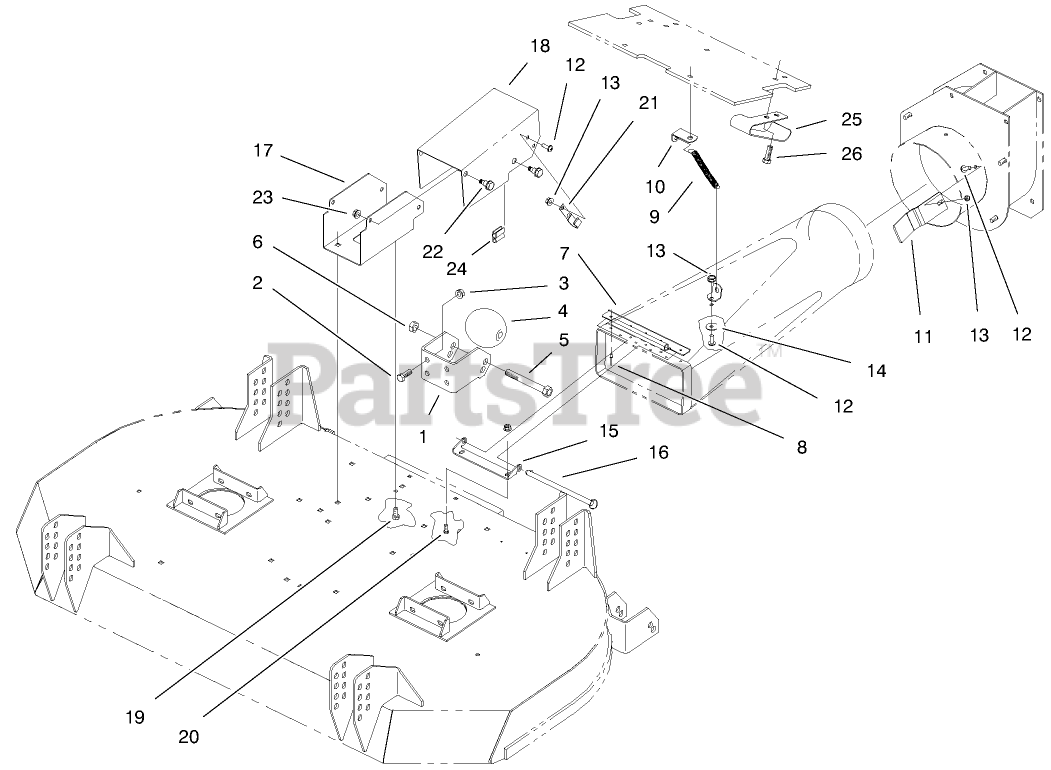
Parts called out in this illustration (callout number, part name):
1	BRACKET - ROLLER
2	SCREW-HH
3	NUT-LOCK, NI
4	ROLLER
5	SCREW-HH
6	NUT-LOCK, NI
7	BRACKET - PLENUM
8	RIVET-POP
9	SPRING - EXTENSION
10	BRACKET - SPRING
11	Guide-Plenum
12	SCREW-PPH
13	NUT-HHF
14	WASHER-FLAT
15	BRACKET - HINGE
16	PIN - LOCKING
17	Support-Cover
18	Cover-Driveshaft
19	SCREW-HH
20	SCREW-HH
21	CLIP - CABLE
22	BOLT-SHOULDER
23	NUT-HF
24	STRIP - SEAL
25	Guard-Shaft
26	SCREW-HH
